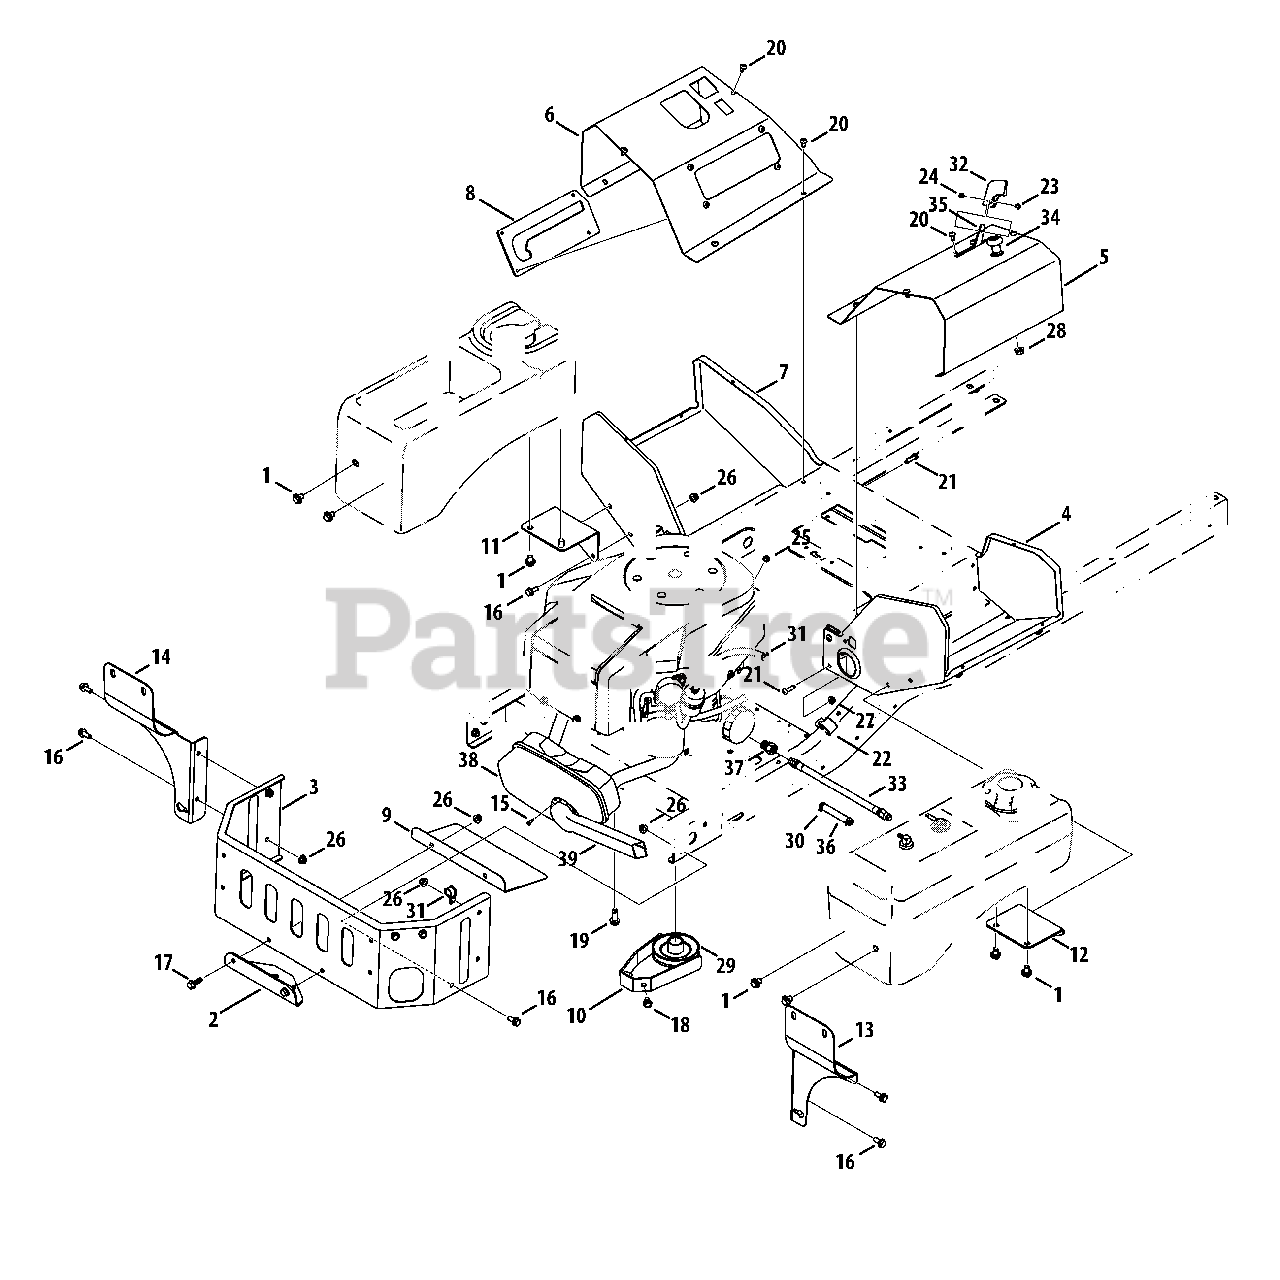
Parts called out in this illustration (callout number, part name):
1	Hex Screw, M10-1.5 x .500 x 8.8
2	Hitch Bracket
3	Bumper Bracket
4	RH Lower Console
5	RH Upper Console
6	LH Upper Console
7	LH Lower Console
8	Parking Brake Lock Bracket
9	Muffler Mount Bracket
10	Belt Keeper Bracket
11	Left Tank Support Bracket
12	Right Tank Support Bracket
13	Tank Support Bracket RH
14	Tank Support Bracket LH
15	Hex Washer Screw, #8-18 x 0.500
16	Hex Flange Screw, 5/16-18
17	Hex Flange, 5/16-18 x 1.0
18	Hex Washer Screw, 5/16-18 x .750
19	Tap Screw, 3/8-16 x 1.25
20	Screw, 1/4-20 x .5
21	Screw, 1/4-20 x 1.0
22	Clamp, 1.0
23	Machine Screw, #8-32 x0.375
24	Hex Nut, #8-32
25	Sems Nut, 1/4-20
26	Flange Lock Nut, 5/16-18
27	Flange Lock Nut, 1/4-20
28	Flange Lock Nut, 3/8-16
29	Electric PTO Engine Pulley
30	Hose Clamp, .490
31	Clamp, 9/16
32	Throttle Knob
33	Oil Drain Extension Hose
34	Choke Cable
35	Throttle Cable, 39.0 x .62
36	Fuel Hose, 1/4
38	Kawasaki Twin Muffler
39	Long Muffler Deflector
